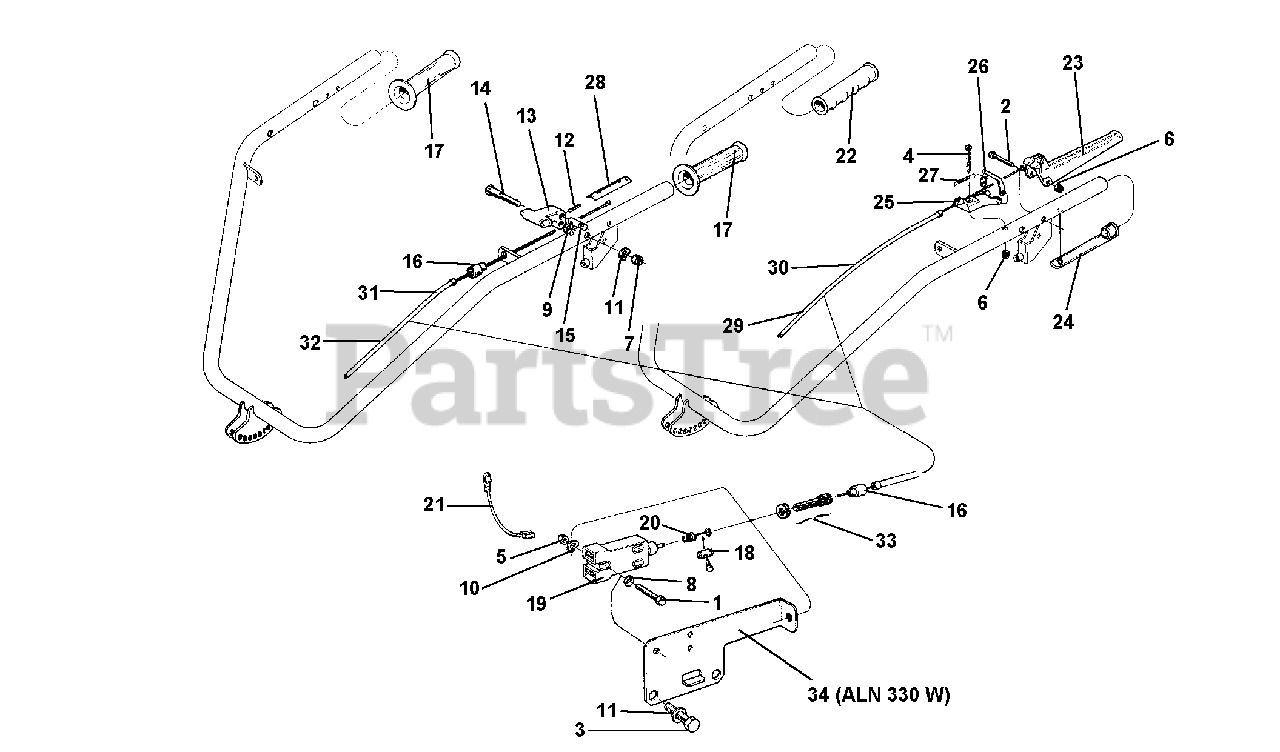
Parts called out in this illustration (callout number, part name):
1	SCREW TE M4 X 25
2	SCREW TE M6 X 45
3	SCREW TE M8 X 12
4	SCREW TSV M6 X 40
6	NUT, SELF LOCKING M6
7	NUT, SELF LOCKING M8
8	FLAT WASHER 4.3
9	WASHER, FLAT 8.4
10	LOCK WASHER B 4.3
11	WASHER, LOCK 8.4
12	PIN, LOCKING 4 X 20
13	LOCKING LEVER
15	DRILLED PIN
16	END, SHEATH
17	KNOB RUBBER HOLE D 25
18	CABLE CLAMP
19	STOP SWITCH
20	SWITCH SPRING
21	SWITCH CABLES
23	MOVABLE MOTOR STOP BODY
25	SHEATH LOCK
26	MOVABLE BODY LOCK
28	RUN-STOP LABEL
29	SHEATH CABLE
30	SHEATH CABLE
31	SHEATH CABLE
32	SHEATH CABLE
33	ADJUSTING SCREW
34	SUPPORT FOR ACME STOP SWITCH
